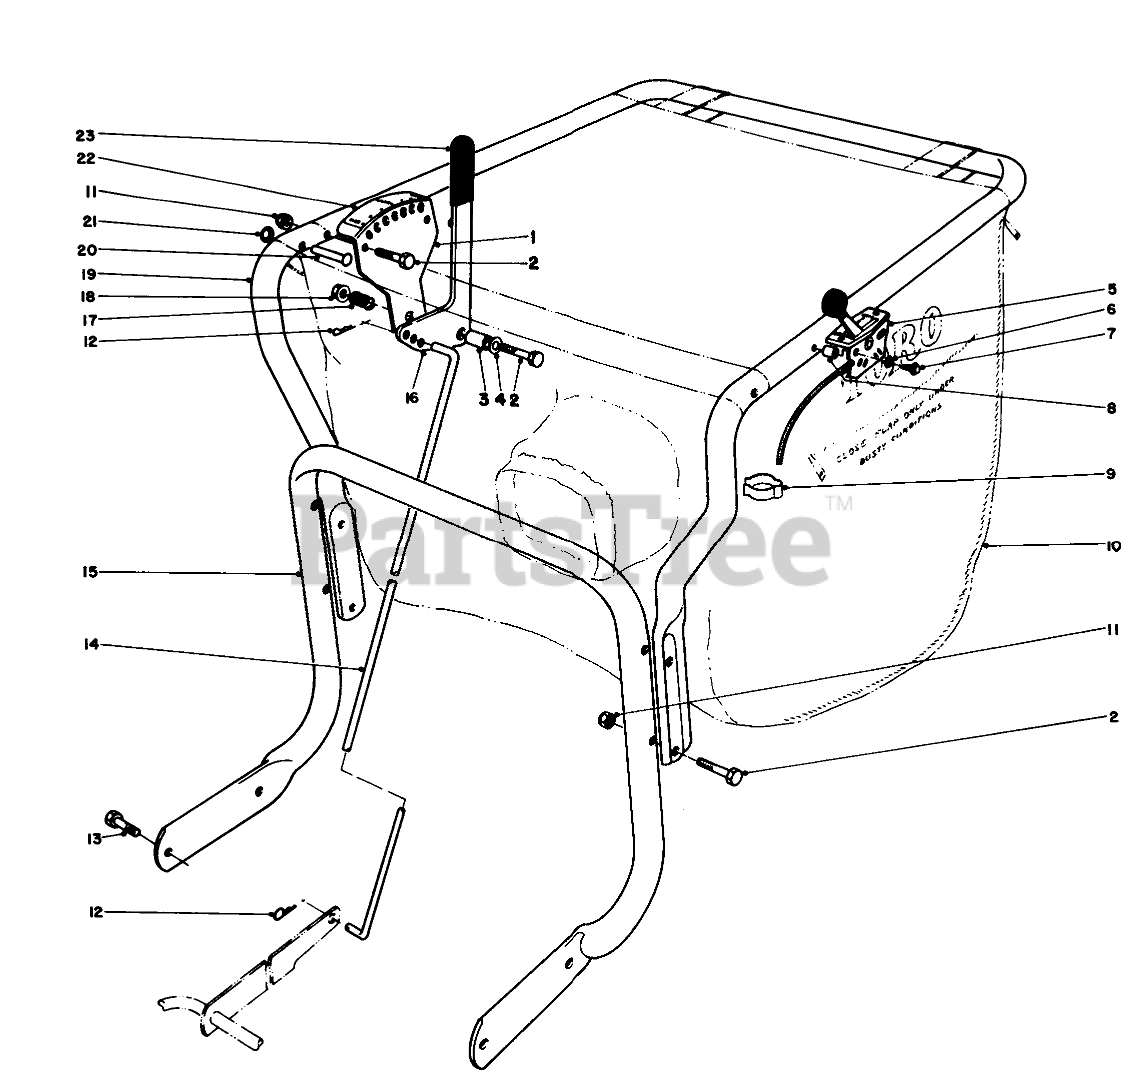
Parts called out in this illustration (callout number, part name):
1	Adjustment Bracket
2	SCREW-HH
3	SPACER
4	WASHER-FLAT
5	THROTTLE CONTROL
6	WASHER-LOCK, EXT
7	10-24 X 1 PAN HD SCR
8	SPACER
9	BODEN CLIP
10	Bag-Vacuum
11	NUT-LOCK, CONE
12	PIN-COTTER
13	SCREW-HH
14	HEIGHT ADJ. ROD
15	HANDLE
16	Handle-Adjustment
17	SPRING-COMPRESSION
18	NUT-HF
19	HANDLE-UPPER, VACUUM
20	RIVET
21	NUT-PUSH IN
22	HT ADJ DECAL
23	GRIP-HANDLE
